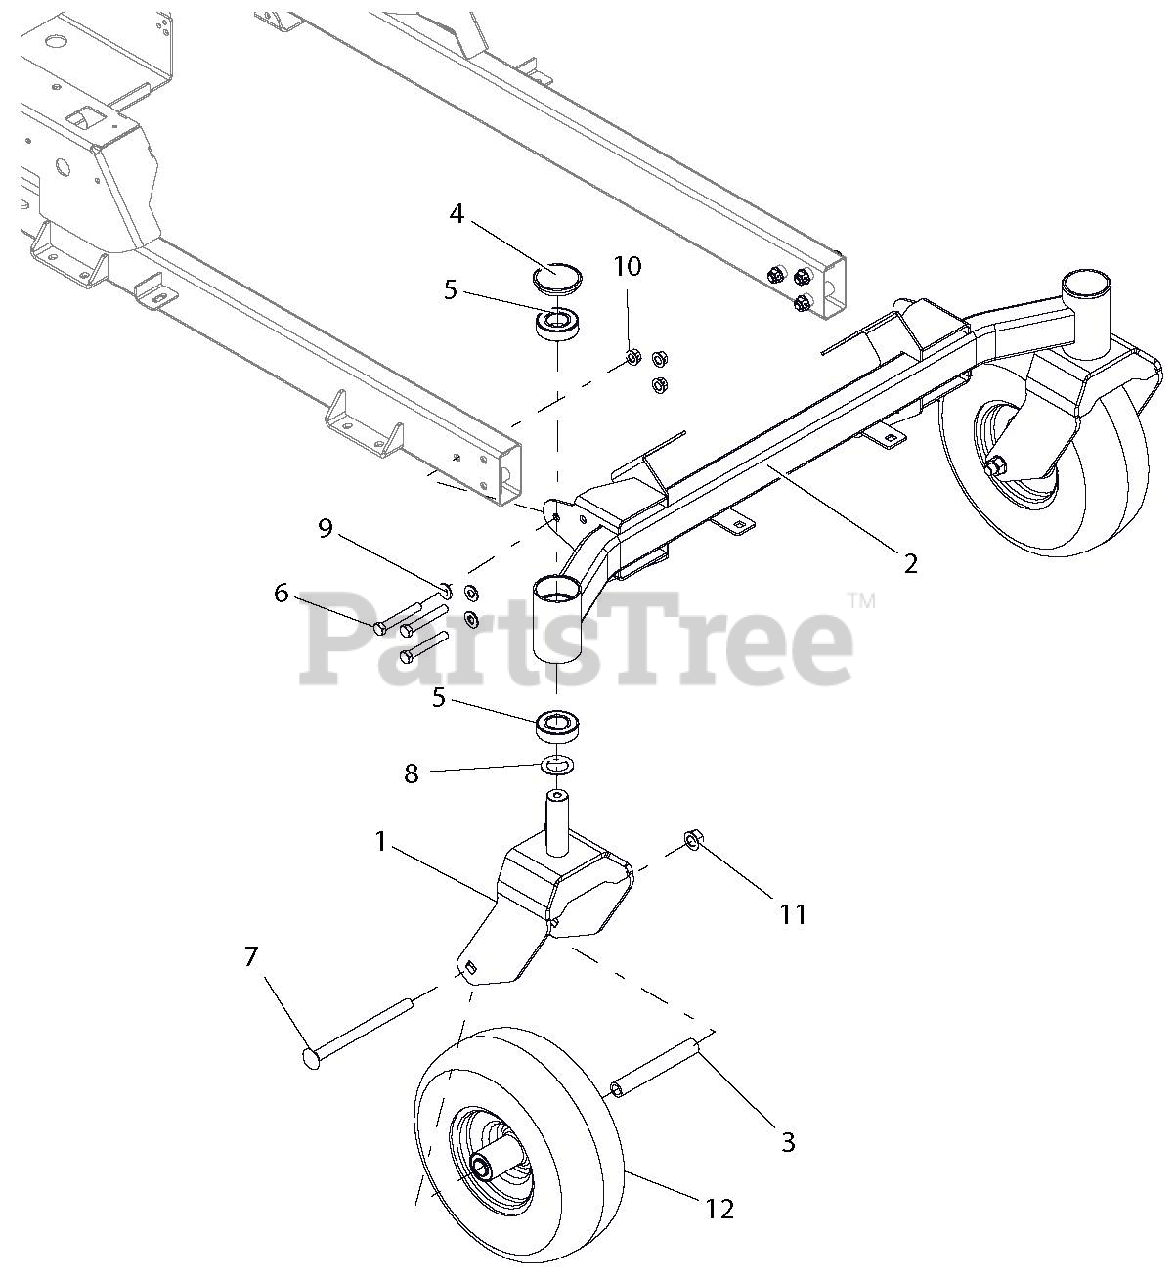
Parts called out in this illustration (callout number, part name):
1	WMT, CASTER FORK
2	WLDMT, AXLE, FRONT
3	SPACER, ROLLED WHEEL
4	CAP, DUST
5	BRG,BALL 1.00X2.00X.563(1641)
6	BLT-HEX .38-16X2.50 GR8 YWZC
7	BLT-RDHDSQNK .50-13X6.50 GR5 Y
8	WSHR-HRD-THRS 1.007X1.542X.062
9	WSHR-HDND .406X.812X.055
10	NUT-LK-TOP-FLG .38-16 GRG YWZC
11	@NUT-LK-TOP-FLG .50-13 YWZC
12	TIRE/WHEEL ASSY, 11X4-5
